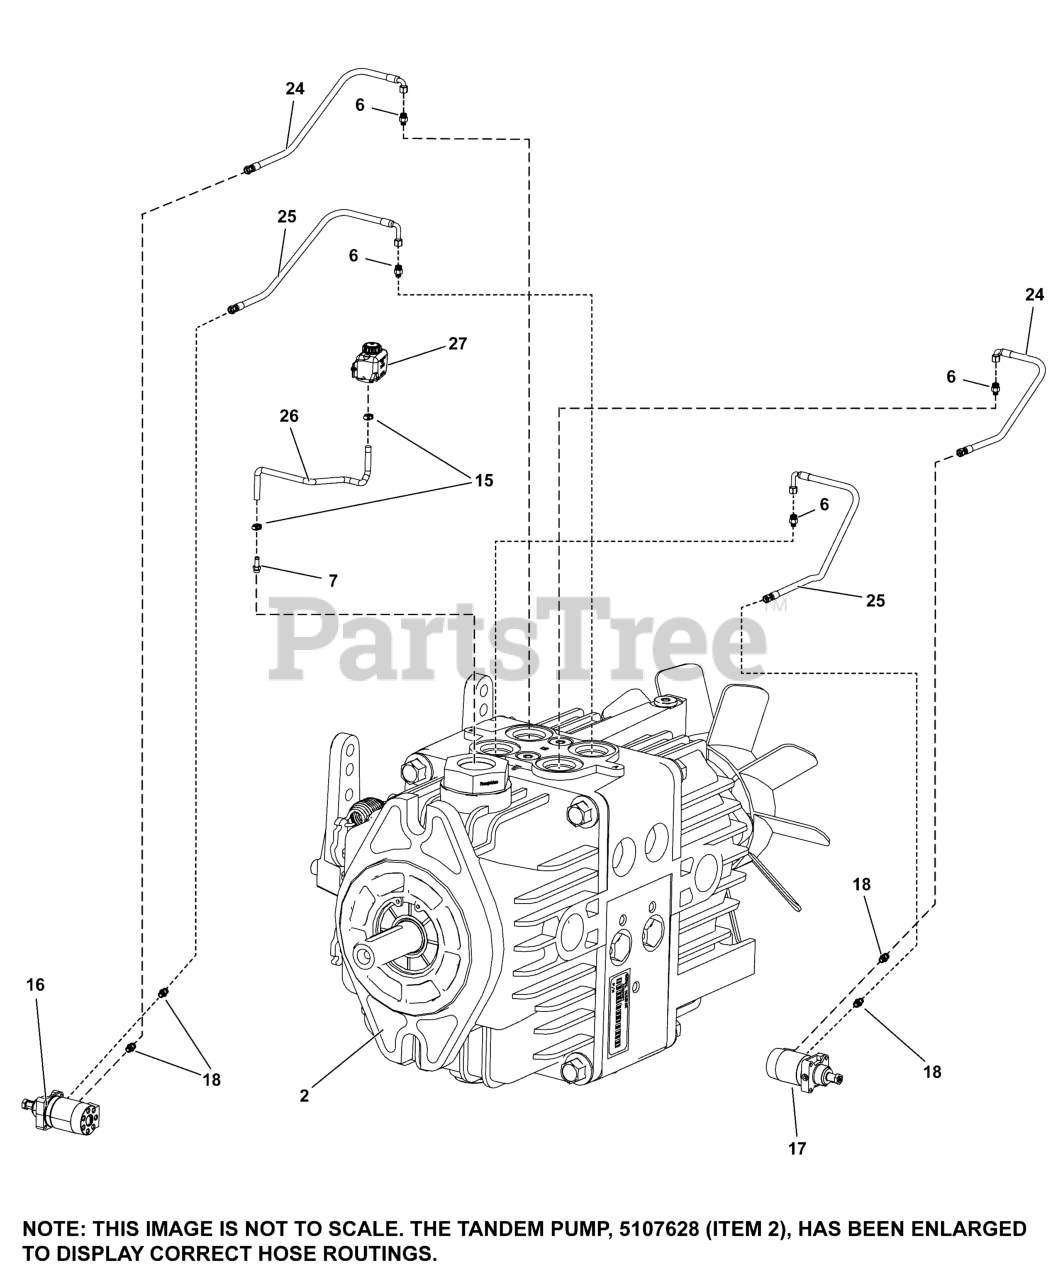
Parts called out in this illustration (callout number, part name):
2	PUMP, TANDEM PARKER HP2
6	ADP-HYD, STR 8 MORB - 10 MORFS
7	FTG-HYD, STR 10 HB X 10 MORB
15	CLAMP, HOSE, WORM GEAR, 11/16" TO 1-1/4"
16	TG0475UB081AAAC LH WHEEL MOTOR
17	TG0475UB080AAVH RH WHEEL MOTOR
18	ADP-HYD, STR 10 MORB - 10 MORFS
24	HOSE, HYDRAULIC ASSY 33.5 SHORT 90
25	HOSE, HYDRAULIC ASSY 35.0 LONG 90
26	HOSE, HYD EXPANSION .625" X 26.5"
27	TANK, EXP. 1 QUART W/ 5/8" STR FITTING
